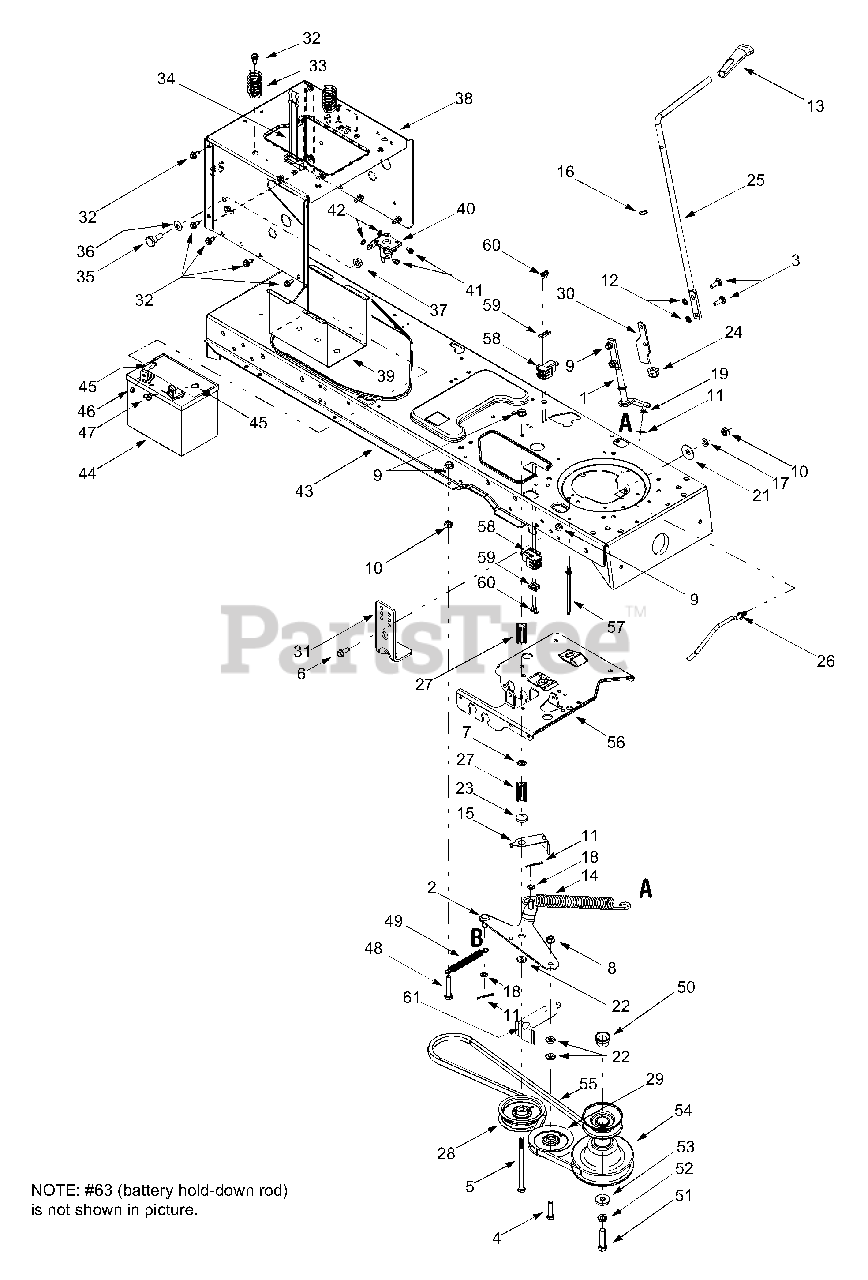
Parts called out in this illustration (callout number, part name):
1	PTO Engage Lever Assembly
4	Hex Cap Screw, 3/8-16 x 1.5
5	Hex Cap Screw, 3/8-16 x 5.5
6	AB Screw 5/16-12 x 0.75
7	Push Nut, 3/8
8	Flange Lock Nut, 3/8-16
9	Flange Lock Nut, 5/16-18
10	Hex Nut, 5/16-18
11	Cotter Pin, 1/8 x 1.25
12	Speed Nut, .3125
13	PTO Knob
14	Extension Spring, .75 x 6.75
16	Flat Washer, .510 x .750 x .033
17	Lock Washer, 5/16
18	Flat Washer, .385 x .62 x .063
19	Flat Washer, 5/16
20	Flat Washer, .406 x .875 x .059
23	Shoulder Spacer, .380
24	Hex Split Flange Bearing, .5
26	Belt Keeper Rod
27	Spacer, 3/8 x 1.54
28	Idler Pulley, 3.5
29	Idler Pulley, 4.0
32	Self Tapping Screw, 5/16-18 x .625
33	Compression Spring, 1.28 x 3.125
34	Battery Strap
35	Shoulder Screw, .625 x .5, 7/16-20
36	Bell Washer, .45 x 1.0 x .062
37	Flange Lock Nut, 7/16-20
41	Self Tapping Screw, 1/4-20 x .5
42	Lock Washer, 1/4
45	Hex Cap Screw, 1/4-20 x .62
46	Hex Sems Nut, 1/4-20
47	Wing Nut, 1/4-20
48	Extension Spring, .50 x 5.0
49	Hex Cap Screw, 5/16-18 x 1.75
50	Spacer Cup
51	Hex Head Cap Screw, 7/16-20 x 1.25
52	Lock Washer, 7/16
53	Flat Washer, .450 x 1.25
54	Engine Pulley, 3.56 OD x 5.56
55	PTO Belt
57	Keeper Pin, 5/16 x 4.75
58	Switch
59	Switch Plate
60	Screw, #10-16 x .5
61	Belt Guard
